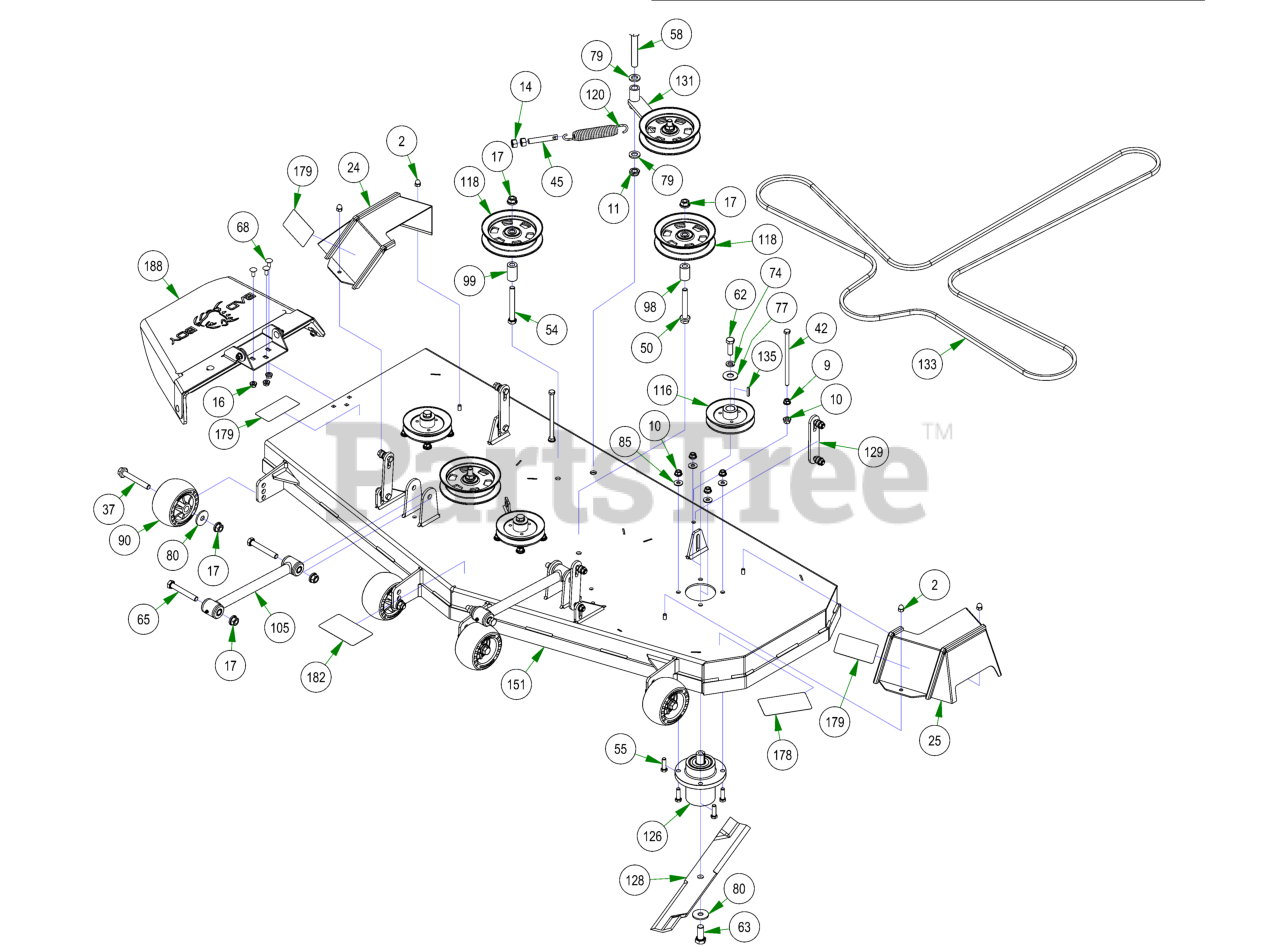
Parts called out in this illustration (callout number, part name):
2	5/16-18 ACORN NUT HIGH-CROWN ZC
9	3/8-16 HEX SERRATED FLANGE NUT HARD/ZINC
10	3/8-16 NYLON INSERT FLANGE LOCKNUT (GR.F) ZINC
11	5/8-11 NYLON INSERT JAM LOCKNUT ZINC
14	1/2-13 HEX NUT ZINC
16	5/16-18 NYLON INSERT FLANGE LOCKNUT ZINC
17	1/2-13 NYLON INSERT FLANGE LOCKNUT ZINC
24	2021 Maverick 54”/60” RH Pulley Cover
25	2021 Maverick 54”/60” LH Pulley Cover
37	1/2-13 X 90MM HEX FLANGE BOLT W/SHOULDER (GR.8) ZINC
42	3/8-16 X 6.5 HEX CAP SCREW (GR.5) ZINC
45	All Thread
50	1/2-13 X 3-1/2 HEX FLANGE BOLT (GR.8) ZINC
54	1/2-13 X 4 HEX CAP SCREW (GR.8) ZINC YELLOW
55	3/8-16 X 1-1/4 HEX CAP SCREW (GR.5) ZINC
58	5/8-11 X 4 HEX CAP SCREW (GR.8) ZINC YELLOW
62	1/2-20 X 1-1/2 HEX CAP SCREW (GR.5) ZINC
63	5/8-18 X 1-1/2 HEX CAP SCREW (GR.8) ZINC YELLOW
65	1/2-13 X 3-1/2 HEX CAP SCREW (GR.5) ZINC
68	5/16-18 x 3/4 Carriage Bolt
74	1/2 SPLIT LOCKWASHER (GR.8) ZINC/YELLOW
77	5/8 USS FLAT WASHER (1-3/4" OD) GR.8 ZINC YELLOW
79	.635 ID X 1.120 OD X .140 THICK FLAT WASHER NYLON
80	1/2 BELLEVILLE WASHER (1-5/8 OD X .140 THK) ZINC
85	5/16 USS FLAT WASHER (7/8 OD) ZINC
90	Deck Wheel
98	.502 ID X .750 OD X 1.500 Long Spacer
99	1 3/4" Pulley Spacer
105	Hybrid Turnbuckle/Deck Locator
116	60" MZ Deck Pulley (Representation Only)
118	5-3/4 Idler Pulley
120	Deck Idler Spring
126	Spindle Assembly-MZ
128	60" High Lift Fusion Blade
129	Deck Hanger Assembly
131	2017 MZ/ZT Deck Idler Assembly
135	3/16 X 1 SQ MACHINERY KEY 1018 STL ZINC
151	2023 60" x 4" Deck
178	2018 60" Deck Decal
179	Danger Decal-Spindle/Discharge
182	Deck Belt Route Decal
188	MZ Discharge Chute Assembly
